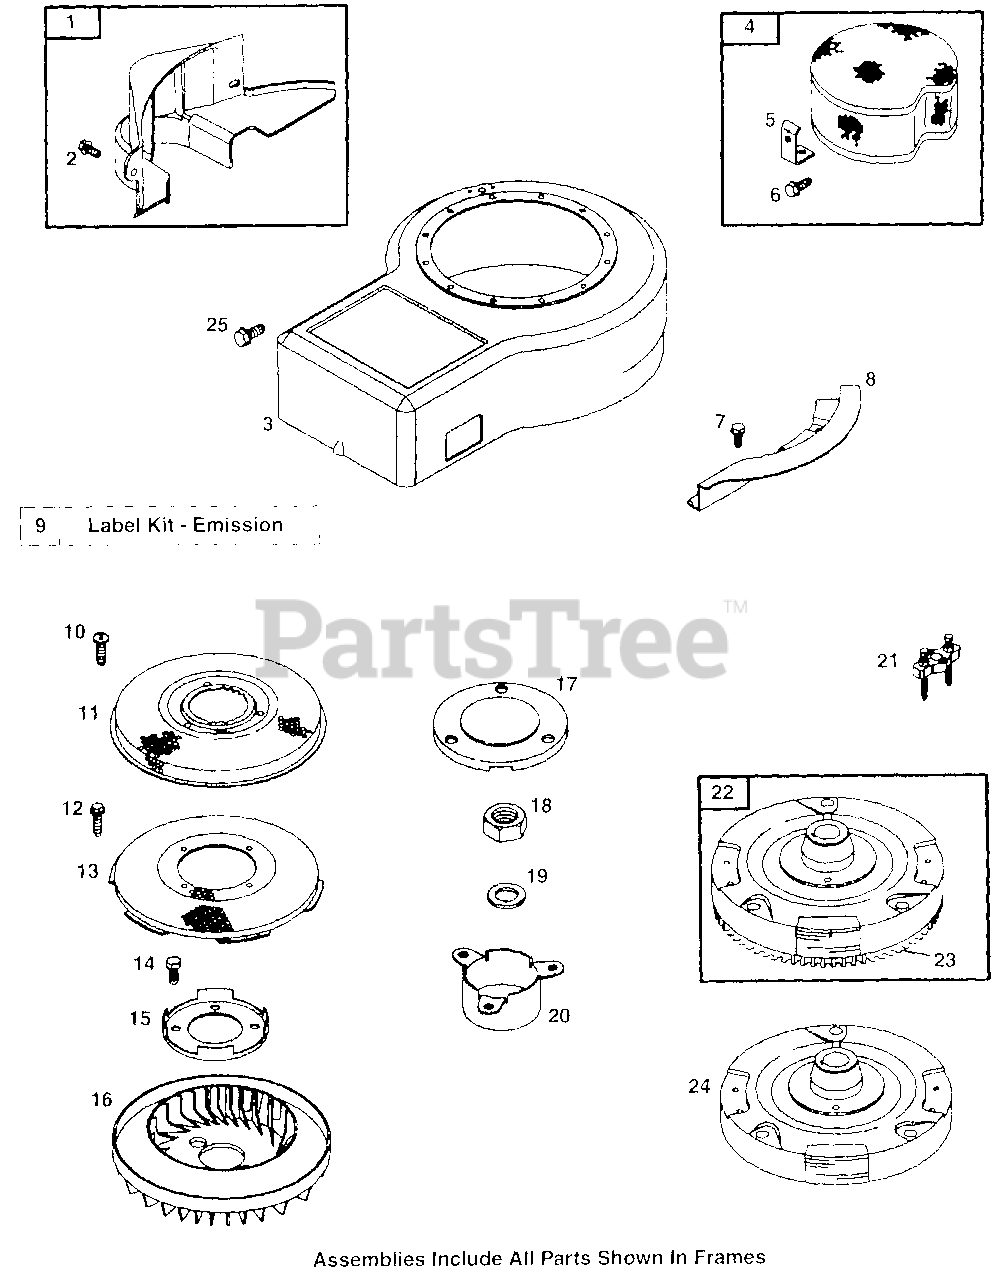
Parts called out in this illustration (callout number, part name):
1	Starter Drive Cover
2	Hex Washer Head Screw
3	Blower Housing (Red)
4	Debris Screen Guard
5	Mounting Bracket
6	Hex Screw
7	Tapping Hex Screw, 8-32 x 3/8
8	Flywheel Guard
9	Label Kit
10	Phillips Screw
11	Rotating Screen
12	Hex Washer Head Screw
13	Rotating Screen
14	Sems Hex Head Screw
15	Fan Retainer
16	Flywheel Fan
18	Flywheel Jam Nut
19	Flat Washer, 5/8
20	Screen Mounting Cup
21	Flywheel Puller
22	Flywheel w/Ring
23	Gear Ring Kit
24	Flywheel Assy for Recoil
25	Machine Hex Screw, 1/2
